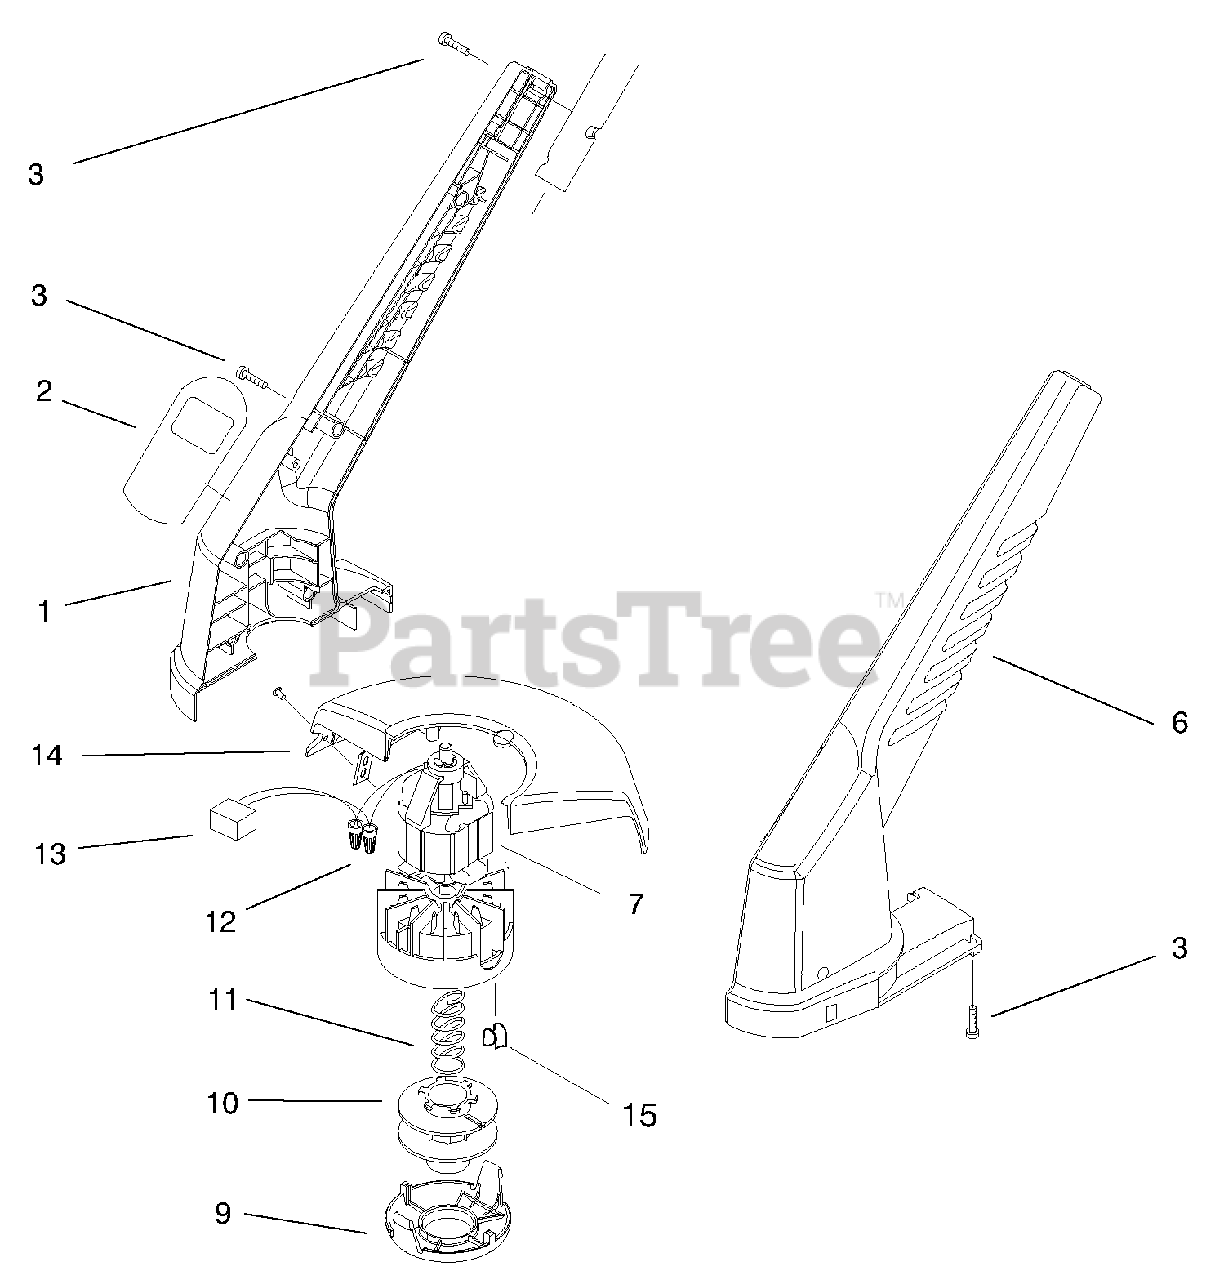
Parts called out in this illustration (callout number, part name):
1	Housing R.H.
2	DECAL 35CM TRIMMER
3	SCREW-PPH
6	Housing L.H.
7	Motor Assembly-Trimmer (Incl. Ref. #15)
10	SPOOL - LARGE
11	SPRING - COMPRESSION
12	CONNECTOR-WIRE NUT
13	FILTER - RFI
14	SHIELD ASM - SERVICE
